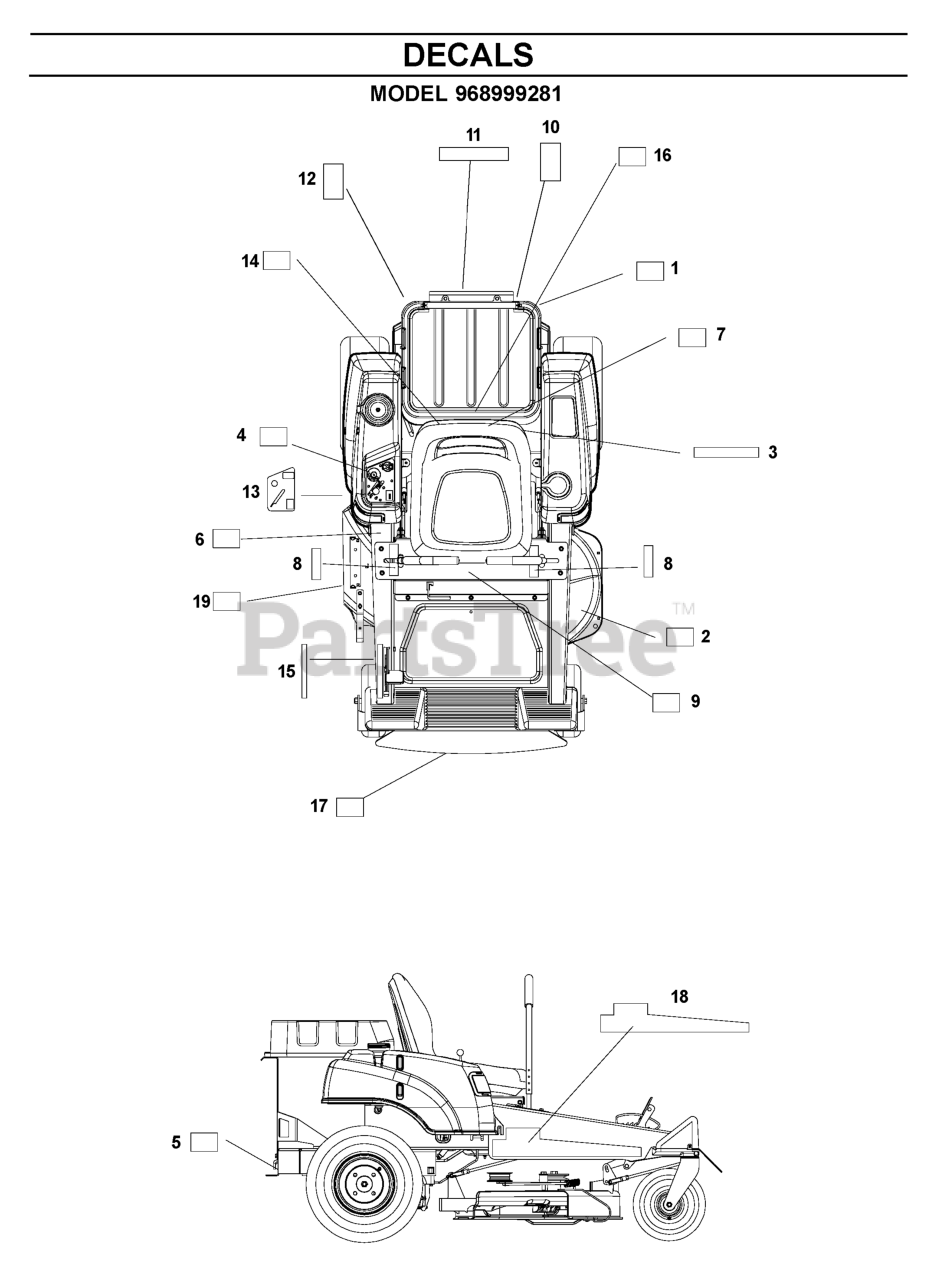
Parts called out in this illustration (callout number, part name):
1	DECAL, PROP. 65
2	DECAL, BELT DRIVE
3	EURO DECAL-BATTERY WARNIN6
4	DECAL, START
5	DECAL, DO NOT TOW
6	DECAL, EXITING MOWER
7	DECAL, SERVICE
8	DECAL, MOTION CONTROL
9	DECAL, SAFETY WARNING
10	DECAL, UTILITY BOX WARNING
11	DECAL, UTILITY BOX PAYLOAD
12	DECAL, PAYLOAD/GASOLINE
13	DECAL, IGNITION CONSOLE
14	DECAL, BELT
15	DECAL, HEIGHT
16	DECAL, CUSTOMER RESPNSIBILITY
17	DECAL, HUSQ 12" BLUE
18	DECAL, Z4218 RESIDENTIAL 20.5"
19	DECAL, CPSC
